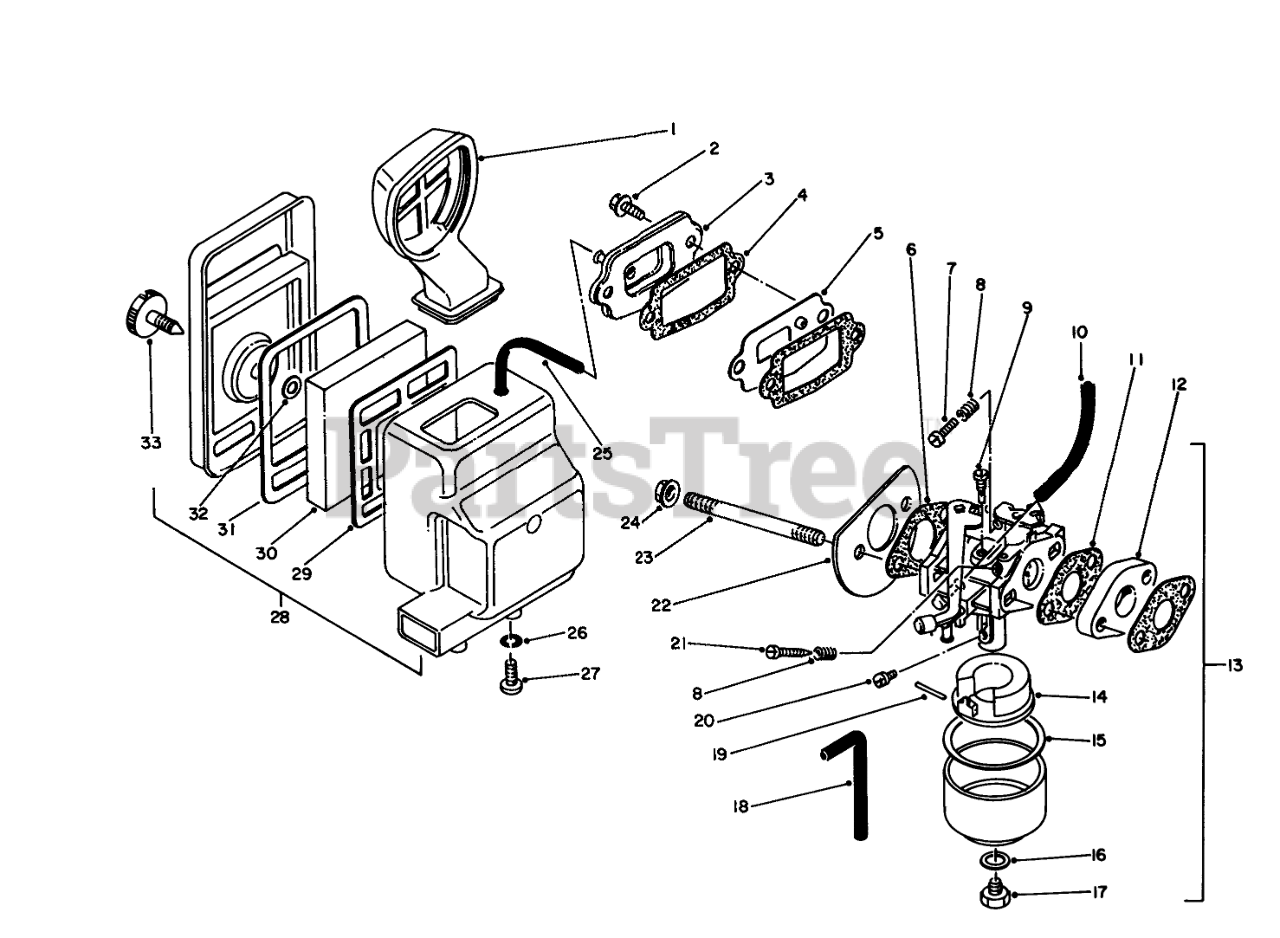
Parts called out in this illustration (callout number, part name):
1	Pipe-Air Cleaner
4	GASKET
5	Valve Assembly-Reed
6	GASKET
7	Screw
8	SPRING
9	PILOT JET
11	Gasket (T:1.0)
12	Insulator (T:10)
13	CARBURETOR ASM
14	Float
15	GASKET
16	GASKET
19	Pin
20	MAIN JET
21	SCREW
22	PLATE
23	Stud Bolt
24	M6 X 1 LOCKNUT
26	Lockwasher
27	Screw
28	Cleaner Assembly-Air
29	Holder
30	AIR CLEANER ELEMENT
31	Gasket
32	Washer
